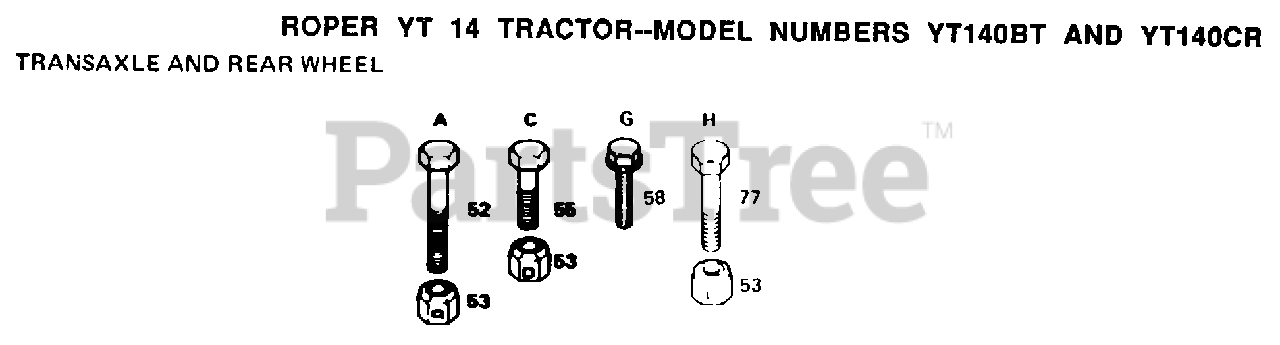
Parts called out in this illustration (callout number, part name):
52	BOLT
58	SCREW
77	BOLT
